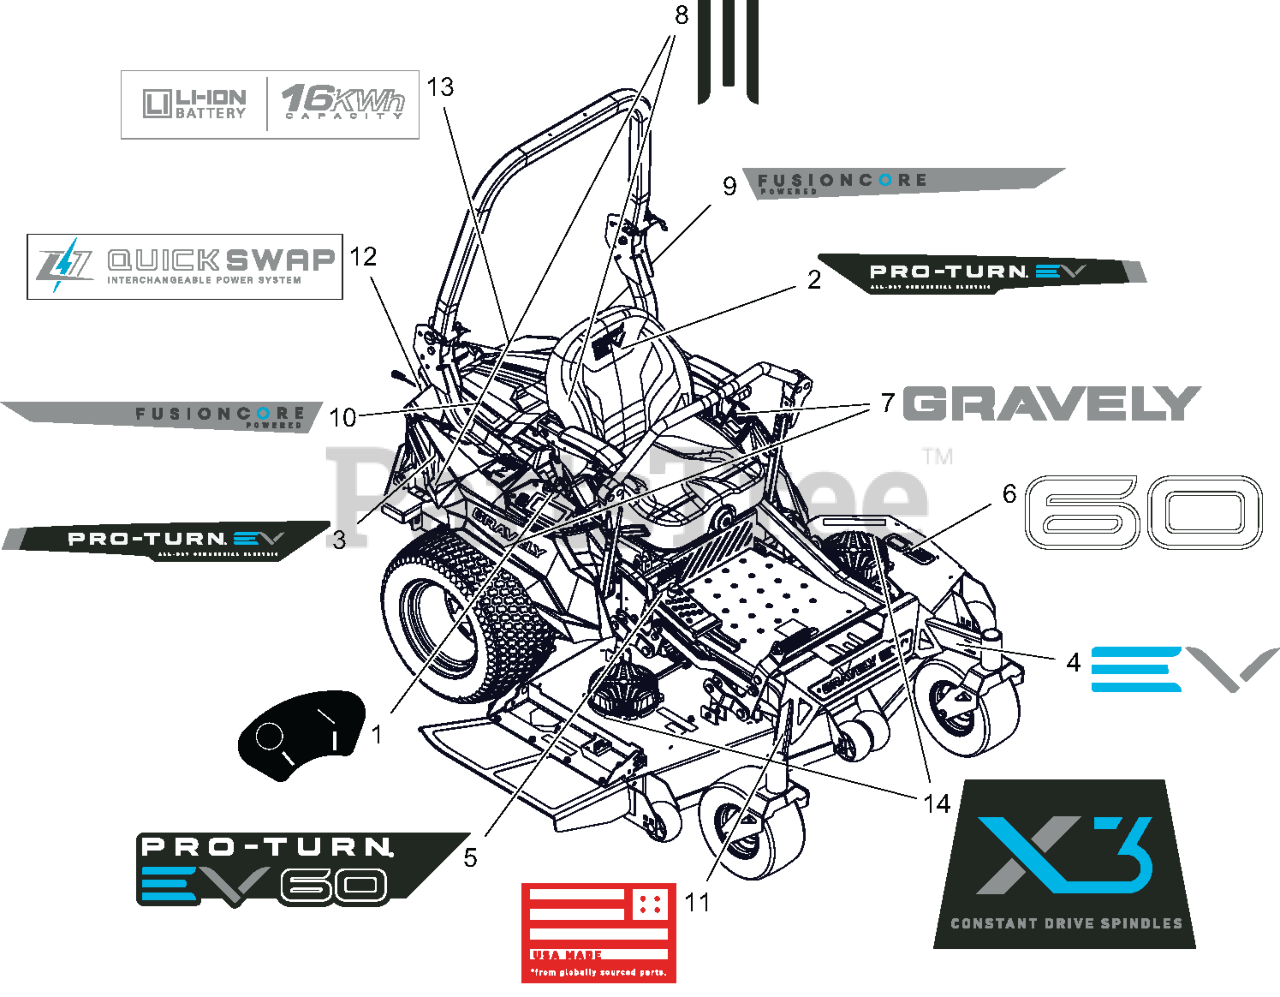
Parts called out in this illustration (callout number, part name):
1	DECAL, KEY SWITCH - 2POS
2	DECAL, FENDER - LH
3	DECAL, FENDER - RH
4	DECAL, FRONT FORK
5	DECAL, KICK PLATE
6	DECAL, DECK - 60"
7	DECAL, GRAVELY LOGO
8	DECAL, STRIPE
9	DECAL, FUSION CORE - LEFT
10	DECAL, FUSION CORE - RIGHT
11	DECAL, USA MADE
12	DECAL, QUICK SWAP -HATCH
13	DECAL, LI- ION - HATCH
14	DECAL, DECK MOTOR
